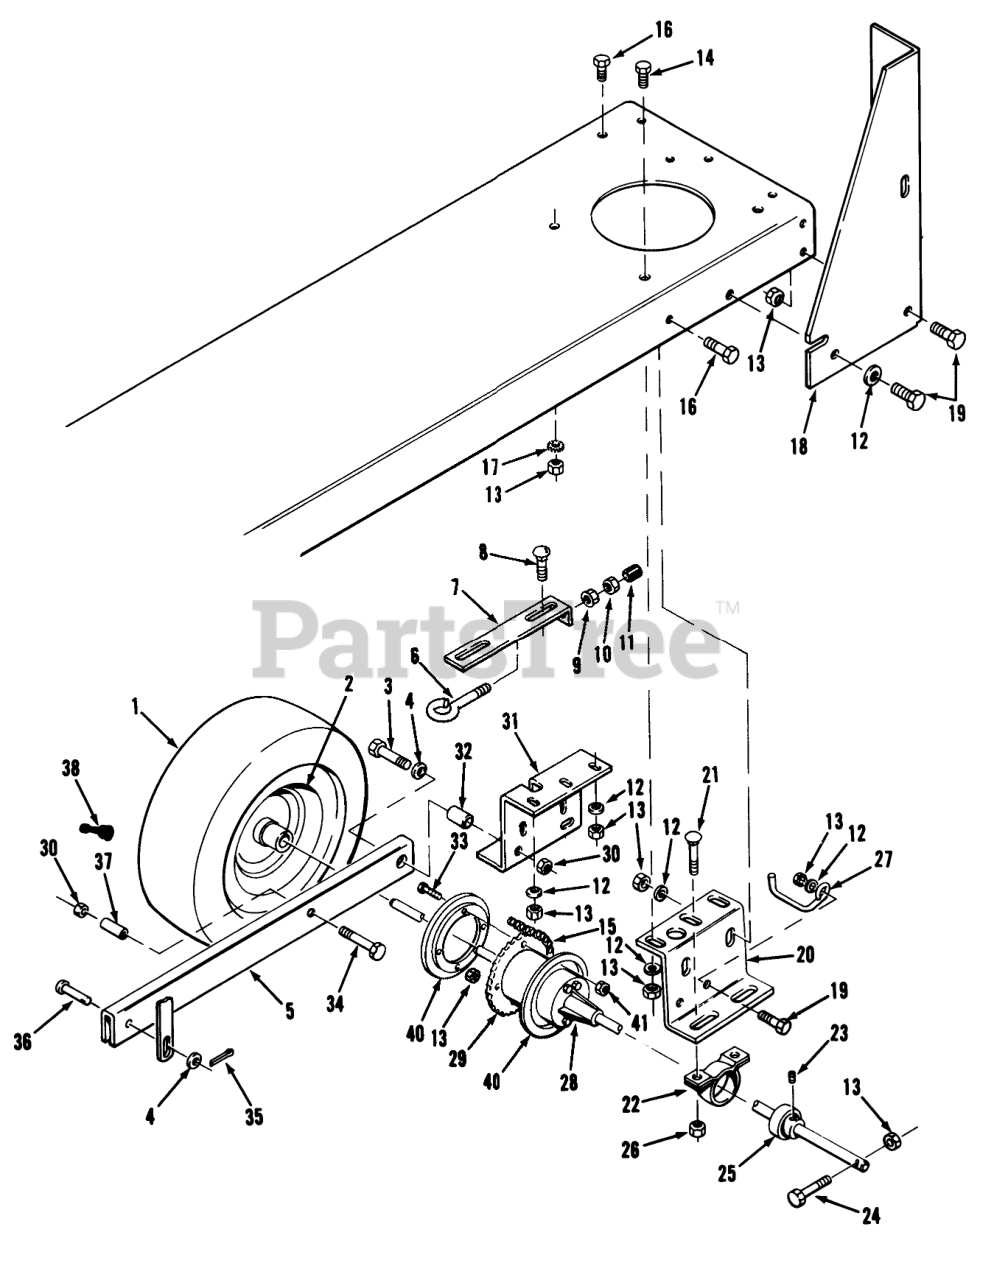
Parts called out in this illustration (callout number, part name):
3	SCREW-HH
4	WASHER-FLAT
5	Arm-Suspension R.H.
6	SCREW-ADJUSTING
7	PLATE-ADJUSTING
8	BOLT-CARR
9	NUT-HF
10	NUT-HEX
11	VINYL ROD TIP
12	WASHER-PLAIN
13	NUT-LOCK, NI
14	SCREW-HH
15	ROLLER CHAIN
16	SCREW-HH
17	WASHER-LOCK, INTERNAL
18	LH STANDBAR B
19	SCREW-HH
20	LH REAR AXLE SUPT R
21	SCREW-CARR
22	RTNR-PILLOW BLK
23	SCREW-SET, HSH
24	Bolt
25	Bearing (Includes Reference #23)
26	NUT-HF
27	BELT GUIDE
28	DIFFERENTIAL
29	SPROCKET
30	NUT-LOCK, CONE
31	RH AXLE SUPPORT R
32	PIN-SUPT ARM
33	SCREW-HH
34	SCREW-HH
35	PIN-COTTER
36	PIN-CLEVIS
37	SPACER-SPLIT TUBE
38	STEM-VALVE
39	TUBE-INNER
40	Guide-Chain
41	NUT-LOCK, CONE
